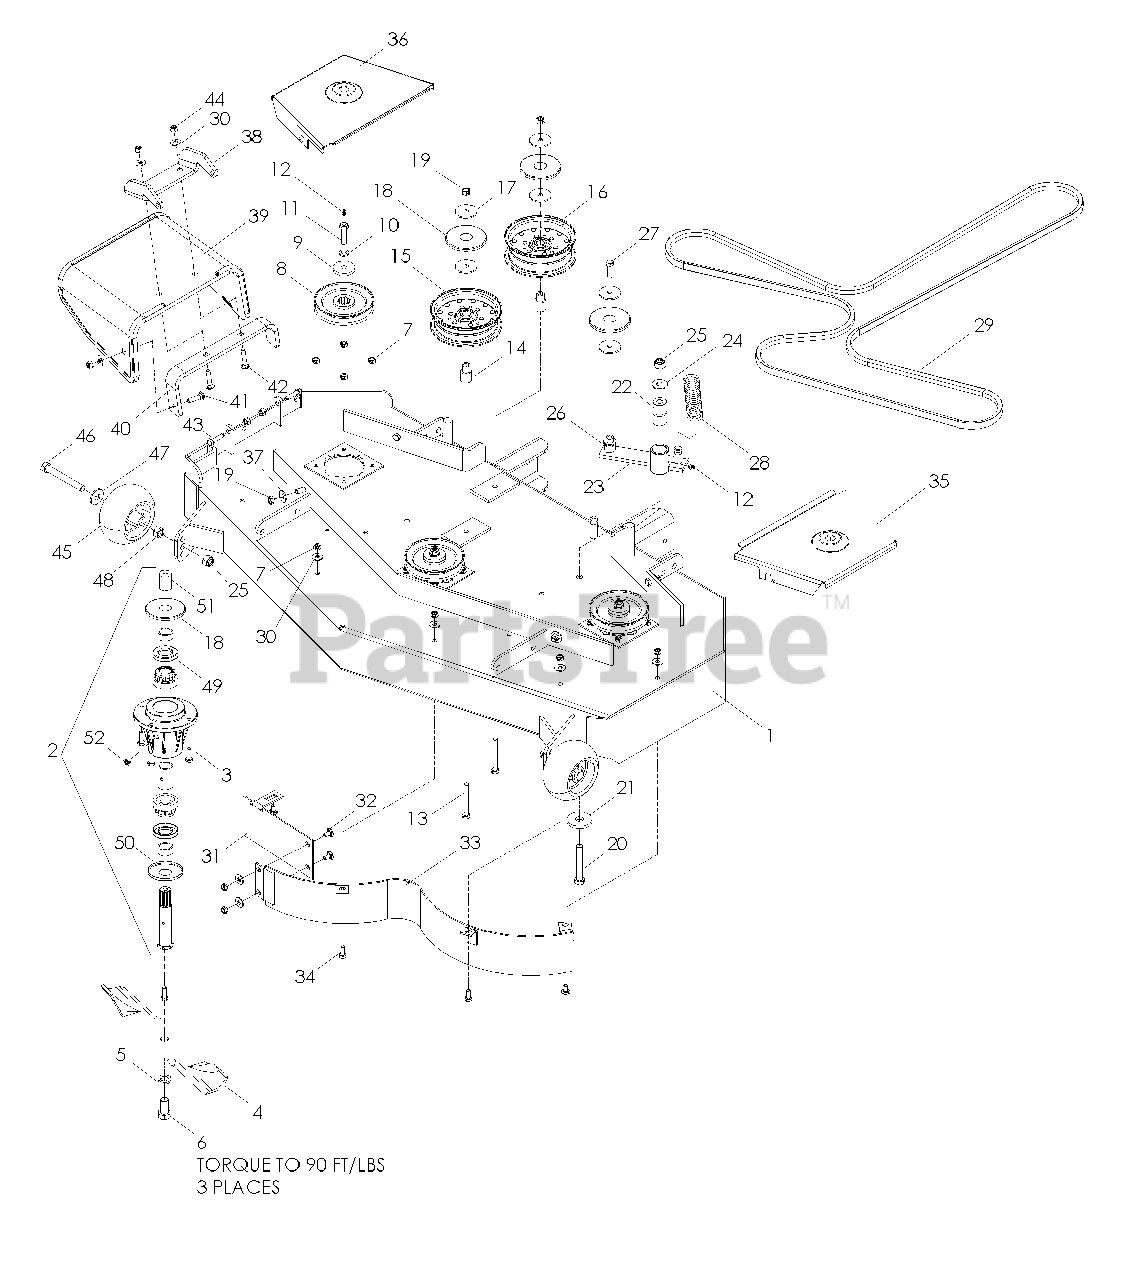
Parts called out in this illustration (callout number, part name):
1	DECK W/DECALS
2	SPINDLE ASM
3	HCS 5/16-18 x 1
4	BLADE 16 1/4
5	WASHER 5/8 SLW
6	HCS 5/8-18 x 1 1/4
7	NUT 5/16-18 HEX CTRLK
9	WASHER, HEAVY
10	WASHER 7/16 SLW
11	HCS 7/16-20 x 1 1/2 GR8 SPEC
12	ZERK
13	HCS 3/8-16 x 3
14	BUSHING, IDLER
15	PULLEY, IDLER
16	PULLEY, IDLER
17	WASHER 3/8 SPECIAL
18	TOP DUST CAP
19	NUT 3/8-16 HEX CNTRLK
20	HCS 1/2-13 x 3 1/4
21	WASHER, SUPPORT
22	BUSHING, PIVOT
23	ARM, IDLER
24	WASHER 1/2 STD FLT
25	NUT 1/2-13 HEX NYLOC
26	BUSHING 5/8 MACHINERY
27	HCS 3/8-16 x 1 1/4
29	BELT, DECK
30	WASHER 5/16 STD FLT
31	BAFFLE, CENTER
32	RHSNB 5/16-18 x 5/8
33	BAFFLE, MAIN
34	HCS 5/16-18 x 3/4
35	SHIELD, LT
36	SHIELD, RT
37	WASHER 3/8 FLAT
38	BRACKET, PIVOT
39	CHUTE, RUBBER
40	REINFORCEMENT, BRACKT
41	RHSNB 5/16-18 x 1 1/4
42	RHSNB 5/16-18 x 1 1/2
43	HCS 5/16-18 x 1 1/4
44	NUT 5/16-18 HEX NYLOC
45	WHEEL, GAUGE
46	HCS 1/2-13 x 4
47	WASHER 1/2 FLAT
48	NUT 1/2-13 HEX
49	SEAL, SHAFT
50	DUST CAP, BOTTOM
51	CAP, VINYL
52	GREASE POPPET
